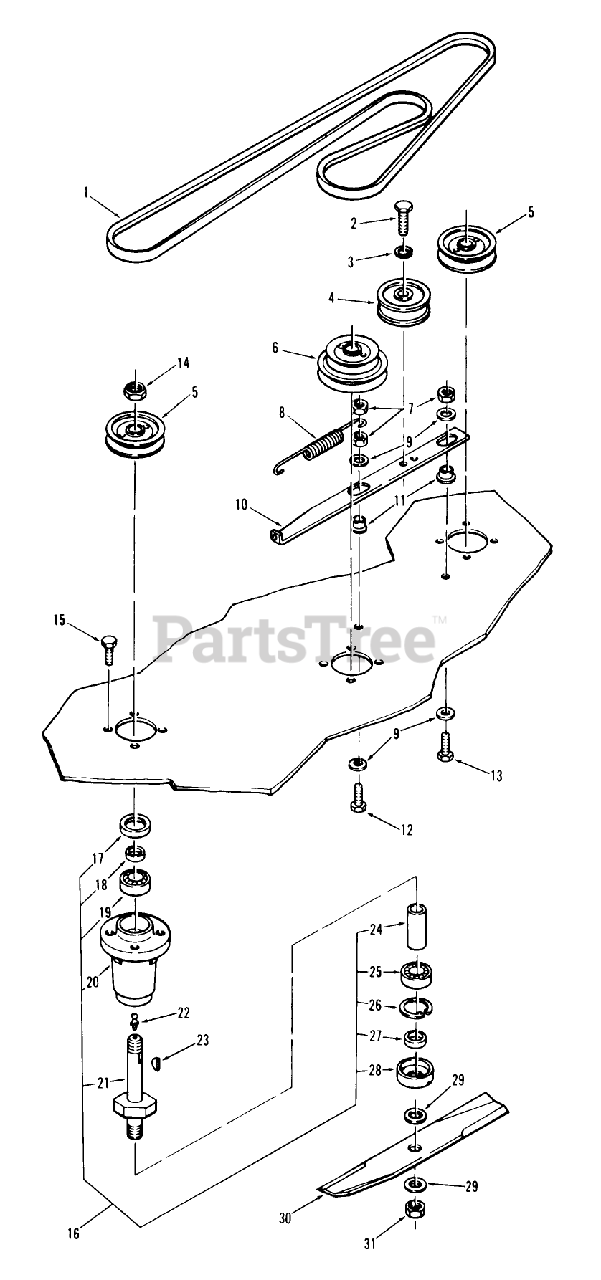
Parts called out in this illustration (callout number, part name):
1	Mower Deck Assembly
2	Grooved Pin 5X28MM
3	Nut
4	CARRIAGE BOLT -4
5	H H C S
6	Roller Shaft
7	SPRING ROLLER STOP
8	Roller
9	Nut
10	PLATE-SPINDLE
11	L.H. Belt Cover
12	R.H. Belt Cover
13	Bolt
14	BOLT-SHOULDER
15	Wheel
16	WASHER
17	LOCKNUT-FLANGE
18	WHEEL SUPPORT LINK
19	Bolt
20	SPACER
21	SUPPORT LINK R
22	Bolt
23	Bracket-Lower R.H.
24	Bracket-R.H. Upper
25	Gage Wheel Support
26	SPRING-COMPRESSION
27	Lever
29	LOCKNUT-FLANGE
30	Quadrant
31	WASHER
32	Bolt
33	Bolt
34	Bracket-L.H. Lower
35	Bracket-L.H. Upper
36	Caution Decal
37	Decal Belt Diagram
